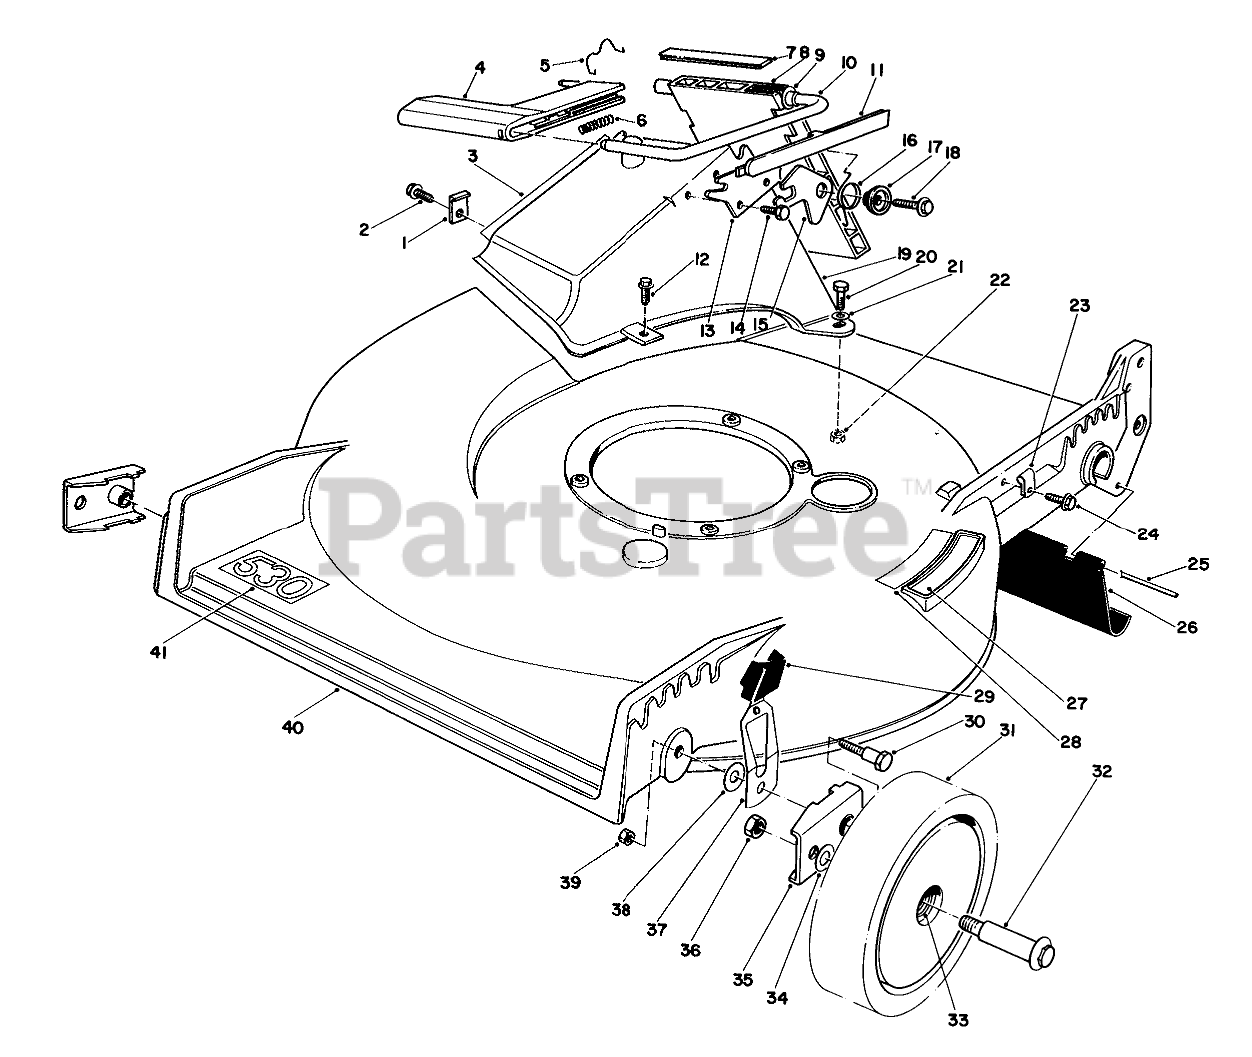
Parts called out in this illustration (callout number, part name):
1	TUNNEL CLIP
2	SCREW
3	Decal-Attention
4	Handle-Door
5	DOOR RET SPRING
6	Spring
7	DOOR COVER
8	Door Discharge
9	BUSHING-NYLON
10	DOOR ROD +
11	DOOR HANDLE COVER
12	Screw
13	DOOR LATCH PLATE
14	SCREW-PLASTITE
15	SAFETY LATCH
16	Spring-Torsion
17	DOOR SPACER
18	SCREW-HWH
19	Tunnel Discharge
20	SCREW-HH
21	WASHER-FLAT
22	NUT-LOCK, NI
23	CLAMP-CABLE
24	SCREW
25	SHIELD ROD
26	SHIELD - TRAILING
27	STEP PAD DECAL
28	Decal-Place Foot Here
29	KNOB-ARM
30	PIVOT SCREW
31	Wheel 8 Tire Assembly (Incl. Ref. #33)
32	Bolt-Wheel
33	Bushing
34	WASHER
35	HP PIVOT ARM ASM
36	Nut
37	Spring Arm
38	WASHER-PIVOT
39	NUT-LOCK, NI
40	21HP RB-SUZ HSG/DECAL
41	Decal-530
